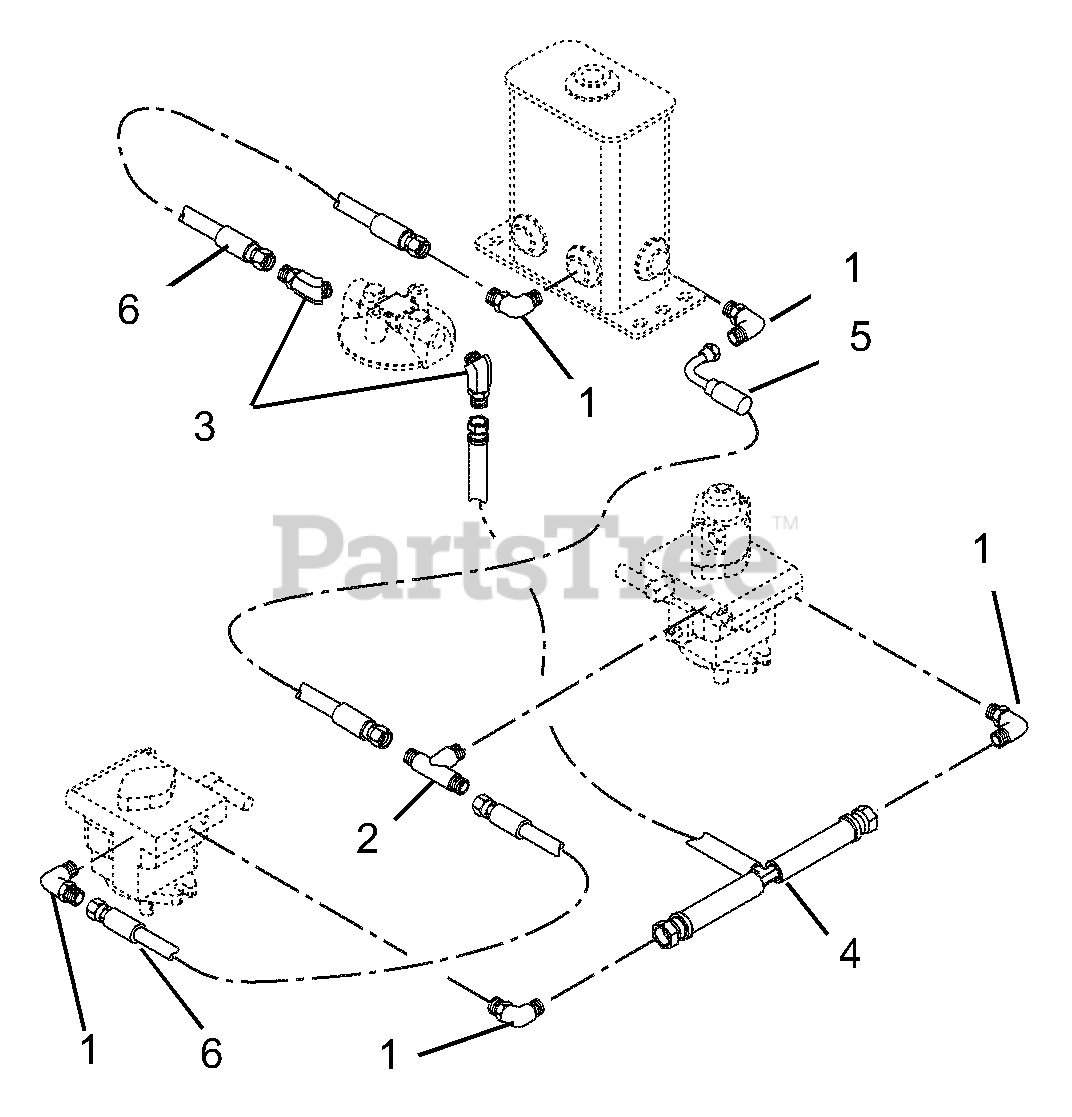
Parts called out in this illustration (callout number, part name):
1	90 Degree Fitting (M8F-M80)
2	Tee Fitting (M80-M80-M80)
3	45 Degree Fitting (M80-M120)
4	Tee Fitting / Hose Assembly (80-80-80)
5	Hydraulic Hose (0.50-19-0KFO8J0-FO8J9)
6	Hydraulic Hose (0.50-16-0KFO8J0-FO8J0)
